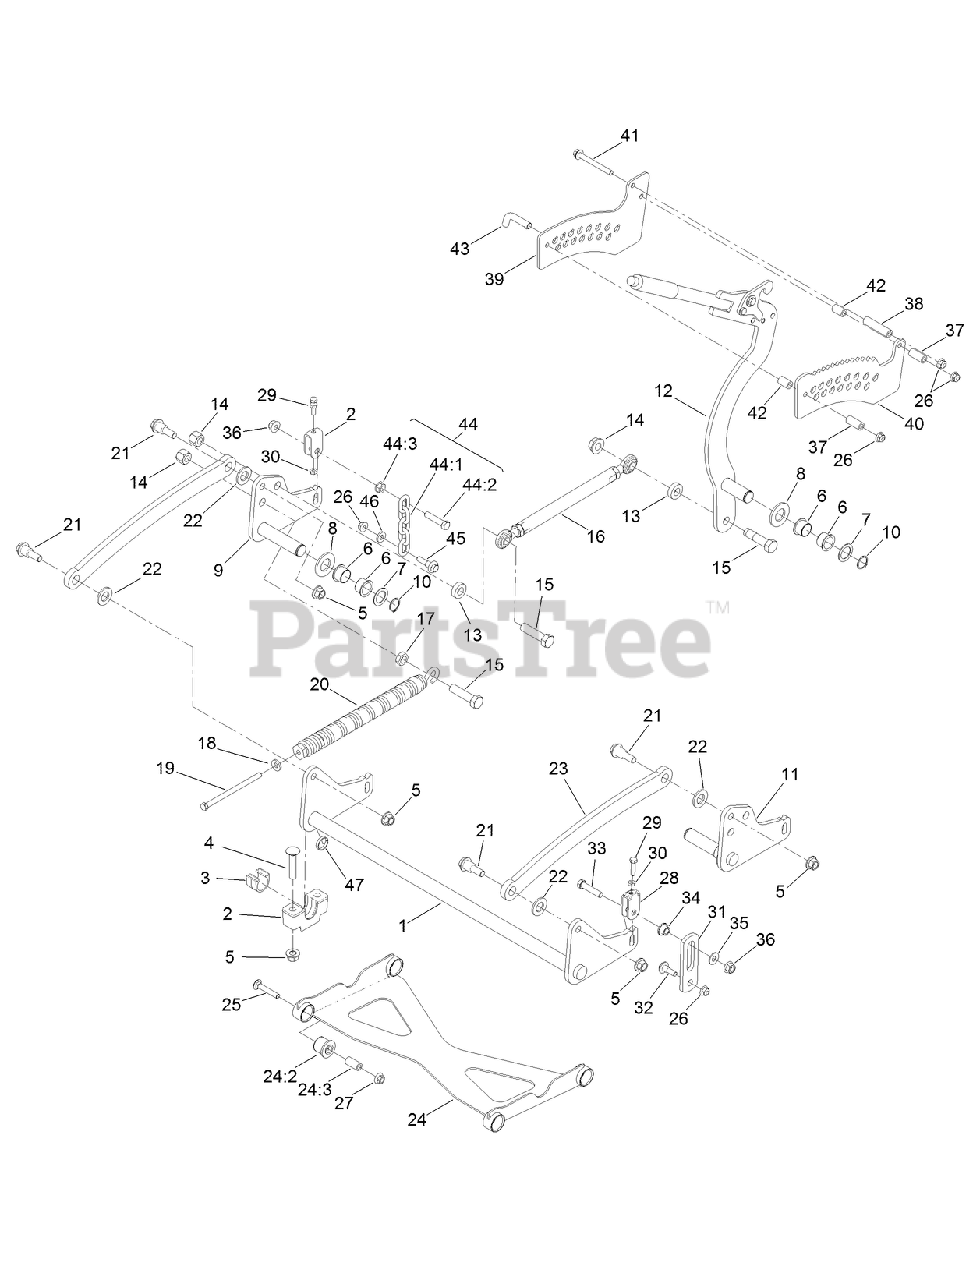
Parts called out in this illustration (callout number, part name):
1	SHAFT-CROSS, FRONT
2	SUPPORT-CROSS SHAFT, BEARING
3	BEARING-CROSS SHAFT, FRONT
4	BOLT-CARR
5	NUT-LOCK
6	BUSHING
8	WASHER-FLAT
9	ARM-LIFT, RH
10	RING-RETAINING
11	ARM-LIFT, LH
12	HOC LEVER ASM
13	WASHER
14	NUT-HEX, CENTER LOCK
15	SCREW-HH
16	HOC LINK ASM
17	NUT-JAM
18	WASHER-BELLEVILLE
19	BOLT-TAP, HH
20	SPRING-EXTENSION
21	SCREW-SHOULDER, HHF
22	WASHER-FLAT
23	LINK-LIFT
24	DECK STRUT ASM
24:2	BUSHING-RUBBER
24:3	SPACER
25	SCREW-HH
26	NUT-HF, NI
27	NUT-HF
28	YOKE-ADJUST, DECK
29	SCREW-HH
30	NUT-JAM
31	LINK-LIFT
32	SCREW-SHOULDER, HHF
33	SCREW-HH
34	BUSHING-FLANGED
35	WASHER-FLAT
36	NUT-HF, NI
37	SPACER
38	SPACER-LONG
39	HOC PLATE AND DECAL ASM
40	PLATE-HOC, INNER
41	SCREW-HHF
42	SPACER
43	PIN-HOC
44	DECK LIFT CHAIN ASM
44:1	CHAIN-LIFT, DECK
44:2	SCREW-HH
44:3	NUT-HF
45	BOLT-SHOULDER
46	SPACER
47	SPACER-SPLIT
